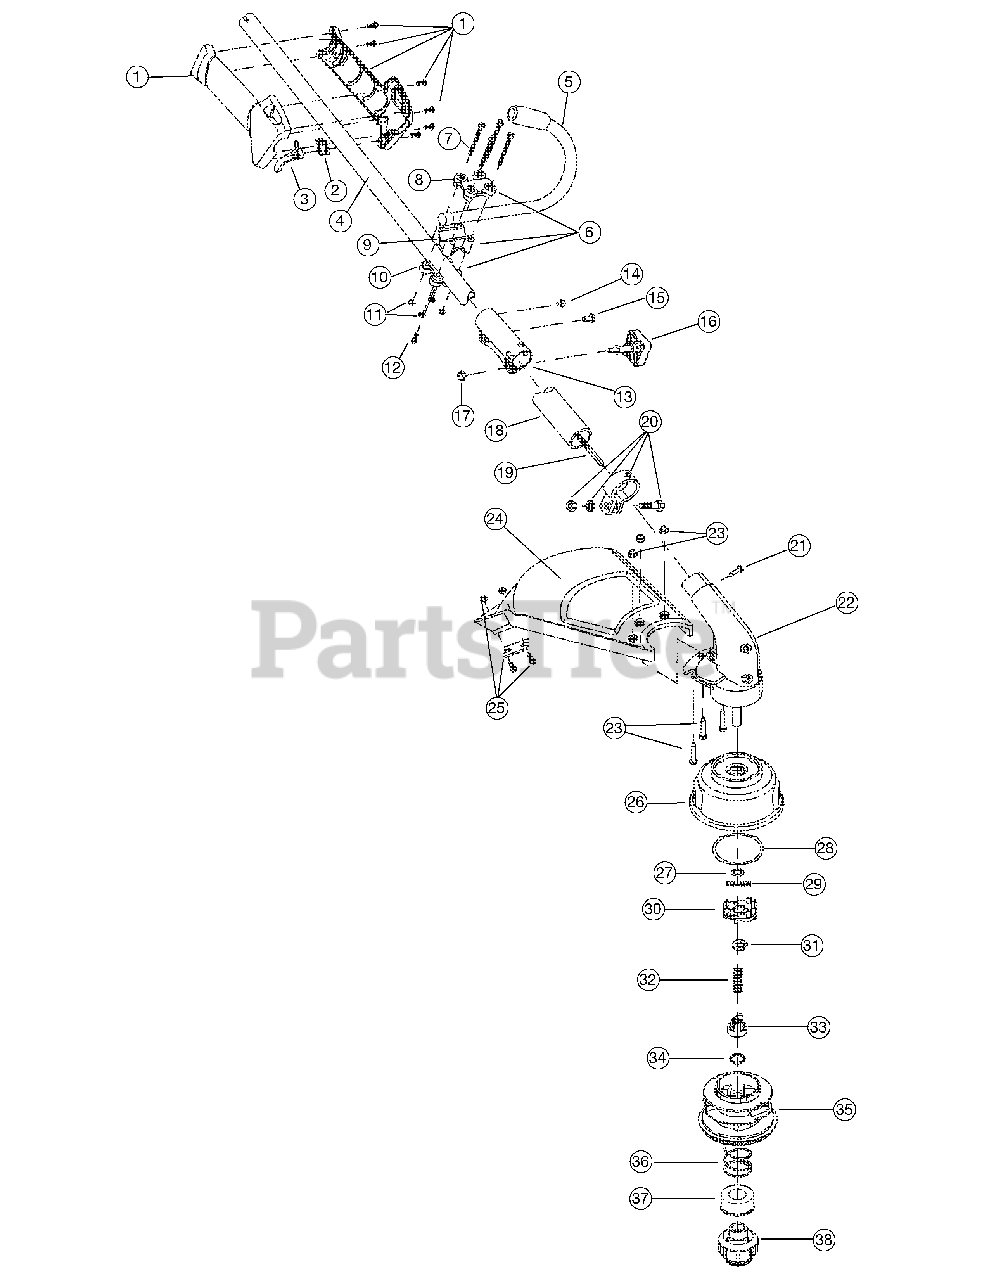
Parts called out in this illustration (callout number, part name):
1	Throttle HousingAssembly (includes 2 & 3)
2	Throttle Trigger Spring
3	Throttle Trigger
4	Upper Drive Shaft Housing Assembly
5	J-Handle Assembly
6	Handle Bracket Assembly (includes 7-12)
8	Upper Handle Clamp
9	Middle Handle Clamp
10	Lower Handle Clamp
12	Anti-Rotation Screw
13	Split Boom Coupler (includes 14-17)
16	Adjustment Knob (Includes 17)
17	Knob Retaining Nut
18	Lower Drive Shaft Housing Assembly
19	Lower Flexible Drive Shaft
20	Lower Clamp Assembly (includes 21)
21	Anti-Rotation Screw
22	Gearbox Assembly (includes 20 & 26-38)
23	Shield Mounting Hardware
24	Shield Assembly (includes 25)
25	Blade Assembly
26	Outer Spool Assembly (includes 27)
27	Retainer
28	Thrust Washer
29	Small Spring
30	Slider
33	Plunger
35	Inner Reel
36	Large Spring
37	Foam Seal
38	Bump Head Knob Assembly (Includes 36 & 37)
